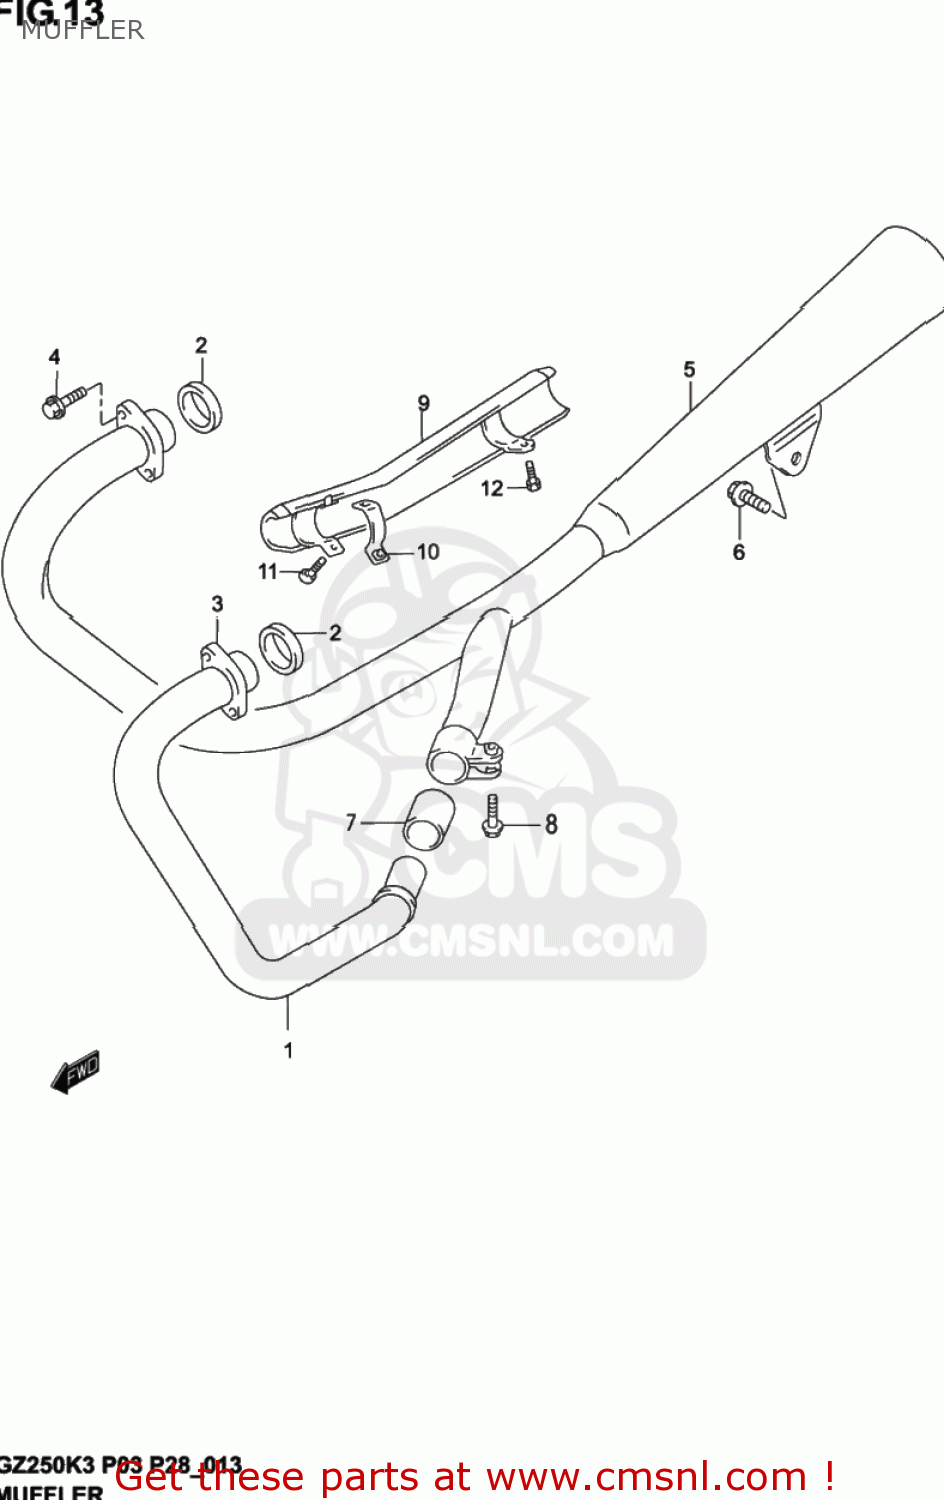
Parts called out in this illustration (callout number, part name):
1	PIPE,EXHAUST,L
2	GASKET,EXHAUST PIPE (NAS)
3	CLAMP,EXHAUST PIPE,L
4	BOLT(6X25)
5	MUFFLER
6	BOLT
7	CONNECTOR,MUFFLER
8	BOLT
9	COVER,MUFFLER
10	CLAMP,MUFFLER COVER
11	SCREW
12	SCREW
